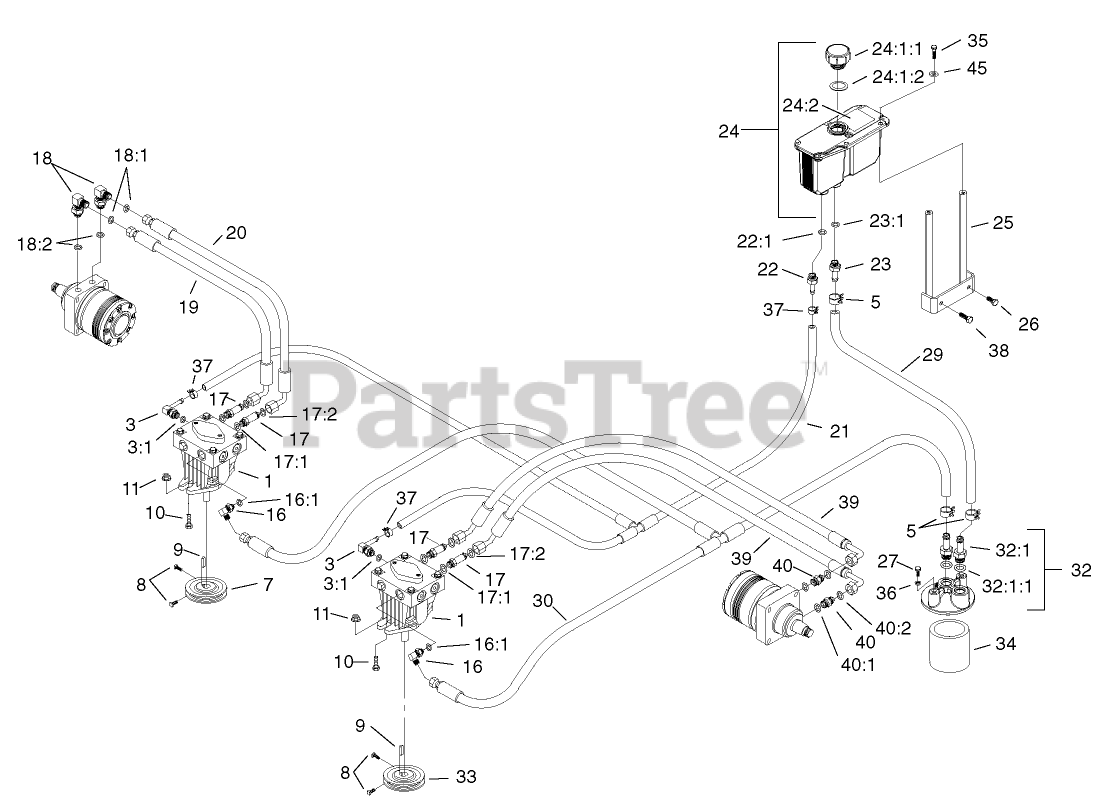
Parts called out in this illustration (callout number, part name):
1	PUMP-HYD
3	ELBOW-90 DEG
3:1	O-RING
5	Clamp-Hose
7	PULLEY
8	SCREW-SET
10	SCREW-HH
11	NUT-HHF, WHIZ
16	FITTING-ELBOW, 90 DEG
16:1	O-RING
17	ADAPTER-HYD, STRAIGHT
17:1	O-RING
17:2	O-Ring
18	FITTING-HYD, 90 DEG
18:1	O-Ring
18:2	O-RING
19	HOSE-FRONT
20	HOSE-REAR, RH
21	HYD HOSE ASM
22	Adapter-Straight
22:1	O-RING
23	ADAPTER-STRAIGHT
23:1	O-RING
24	HYD Reservoir ASM
24:1	Reservoir-HYD
24:1:1	Label-Emissions
24:1:2	GASKET-CAP
24:2	DECAL-TANK, HYD
25	DECAL-EXHAUST
25	STAND-RESERVOIR
26	SCREW-HH
27	SCREW-HH
29	HYD HOSE ASM
30	HYD HOSE ASM
32	Filter Head ASM
32:1	ADAPTER-STRAIGHT
32:1:1	O-RING
33	NUT-HF
34	FILTER-OIL, HYD
34	FILTER-OIL, HYD (WINTER)
35	SCREW-HH
36	WASHER-LOCK
37	Clamp-Hose
38	SCREW-HH
39	Hose-LH
40	Fitting-Straight
40:1	O-RING
40:2	O-Ring
45	WASHER-FLAT
